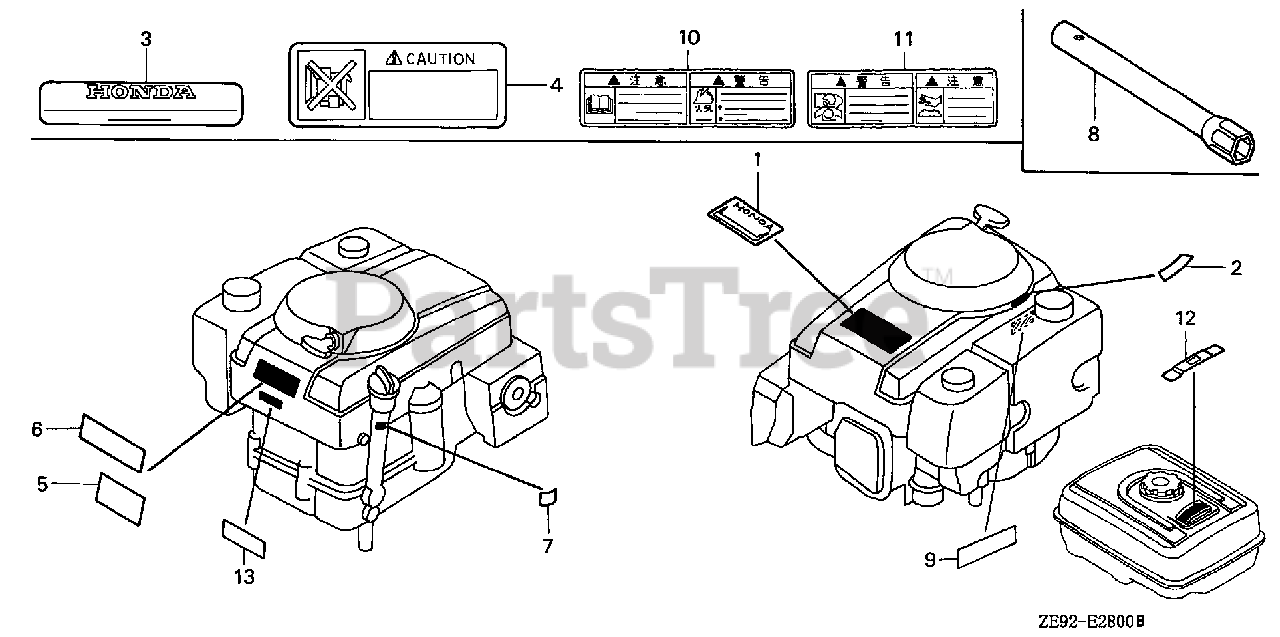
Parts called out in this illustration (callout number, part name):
1	EMBLEM, TOP COVER (11.0)
6	LABEL, CAUTION
7	MARK, TYPE (DN3)
